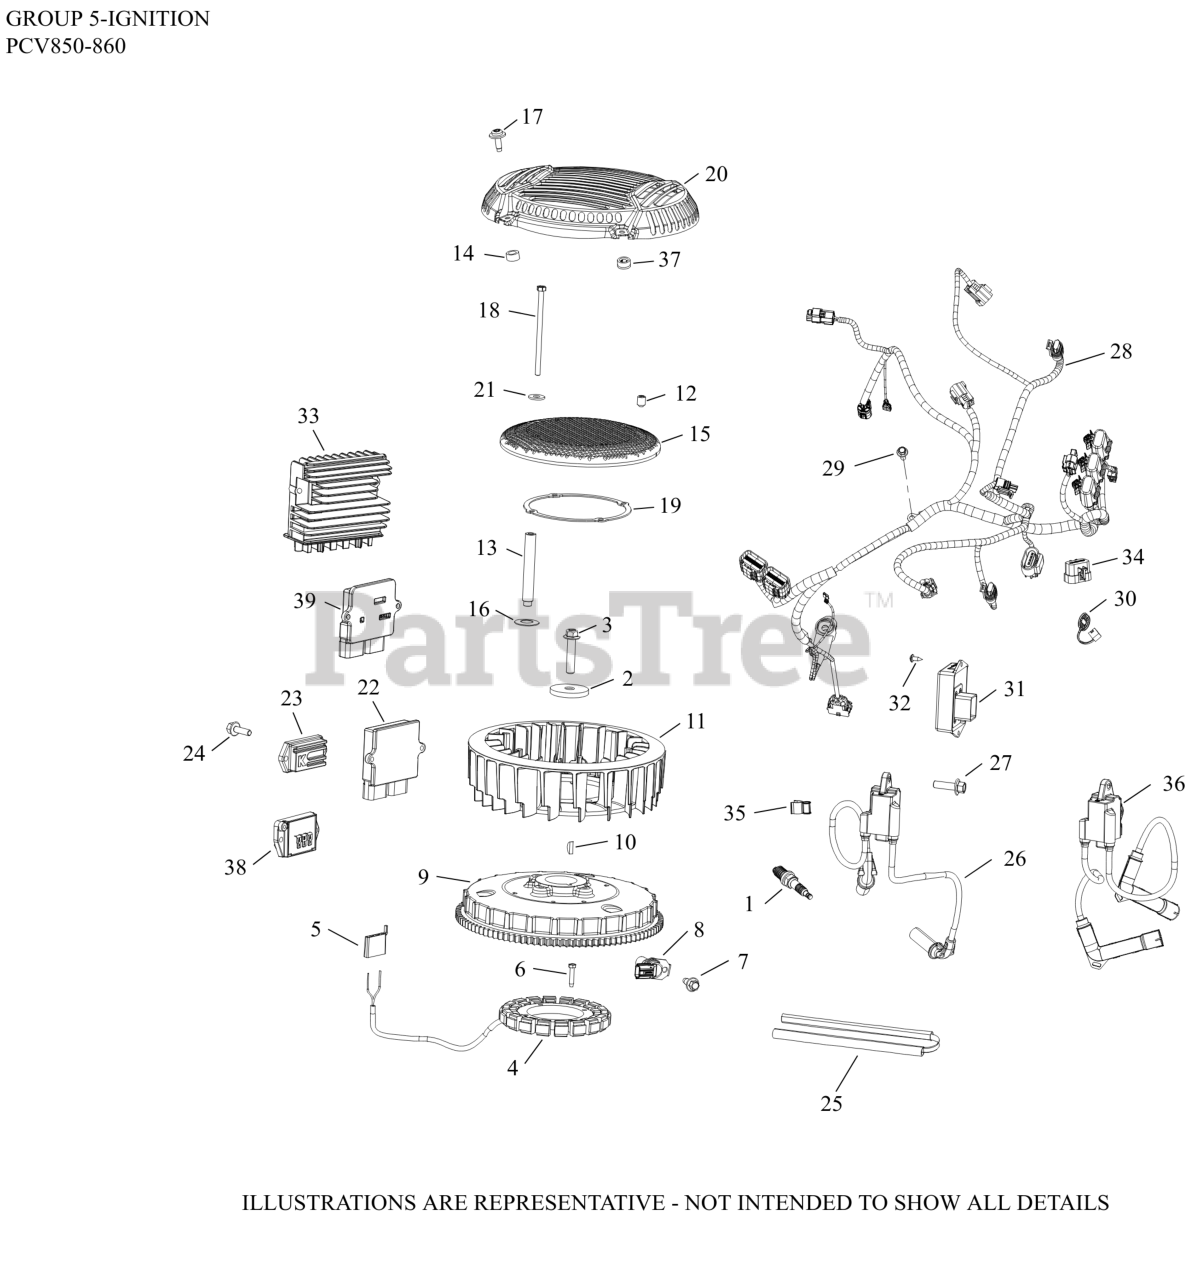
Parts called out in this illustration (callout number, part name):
1	PLUG, SPARK
2	WASHER, FLAT 13/32"
3	SCREW, FLG M10X1.5X45-USE 25 086 361-S
4	KIT, 15 / 20 AMP STATOR
5	CONNECTOR
6	SCREW, THREAD FORMING
7	SCREW, THREAD FORMING
8	SENSOR, SPEED
9	FLYWHEEL, ASSEMBLY
10	KEY, 3/16" X 5/8"
11	FAN
12	SCREW, SKT SET #10-24X1/4"
13	SPACER GRASS SCREEN
14	SPACER-(#2511230S)
14	SPACER .406 X .625 X .344
15	SCREEN, GRASS
16	WASHER, SPRING 10 MM
17	SCREW, SEMS
18	SCREW, HEX HEAD
19	RING, SUPPORT
20	GUARD, GRASS SCREEN (METAL)
21	WASHER, FLAT 1/4" (O.D. 5/8")
22	MODULE, ECU
24	SCREW, HVY FLG M5X.8X16
25	SLEEVE, RFI FLEXIBLE
26	COIL, IGNITION DUAL OUTPUT
27	SCREW, FLG M6x1.0x20
28	HARNESS, WIRING ASSEMBLY - E-GOV-DISC.
29	SCREW, FLG M6X1.0X16
30	CAP, CONNECTOR
31	MODULE, ELECTRONIC GOVERNOR (EFI)
32	SCREW, PAN HEAD
38	REGULATOR, RECTIFIER
